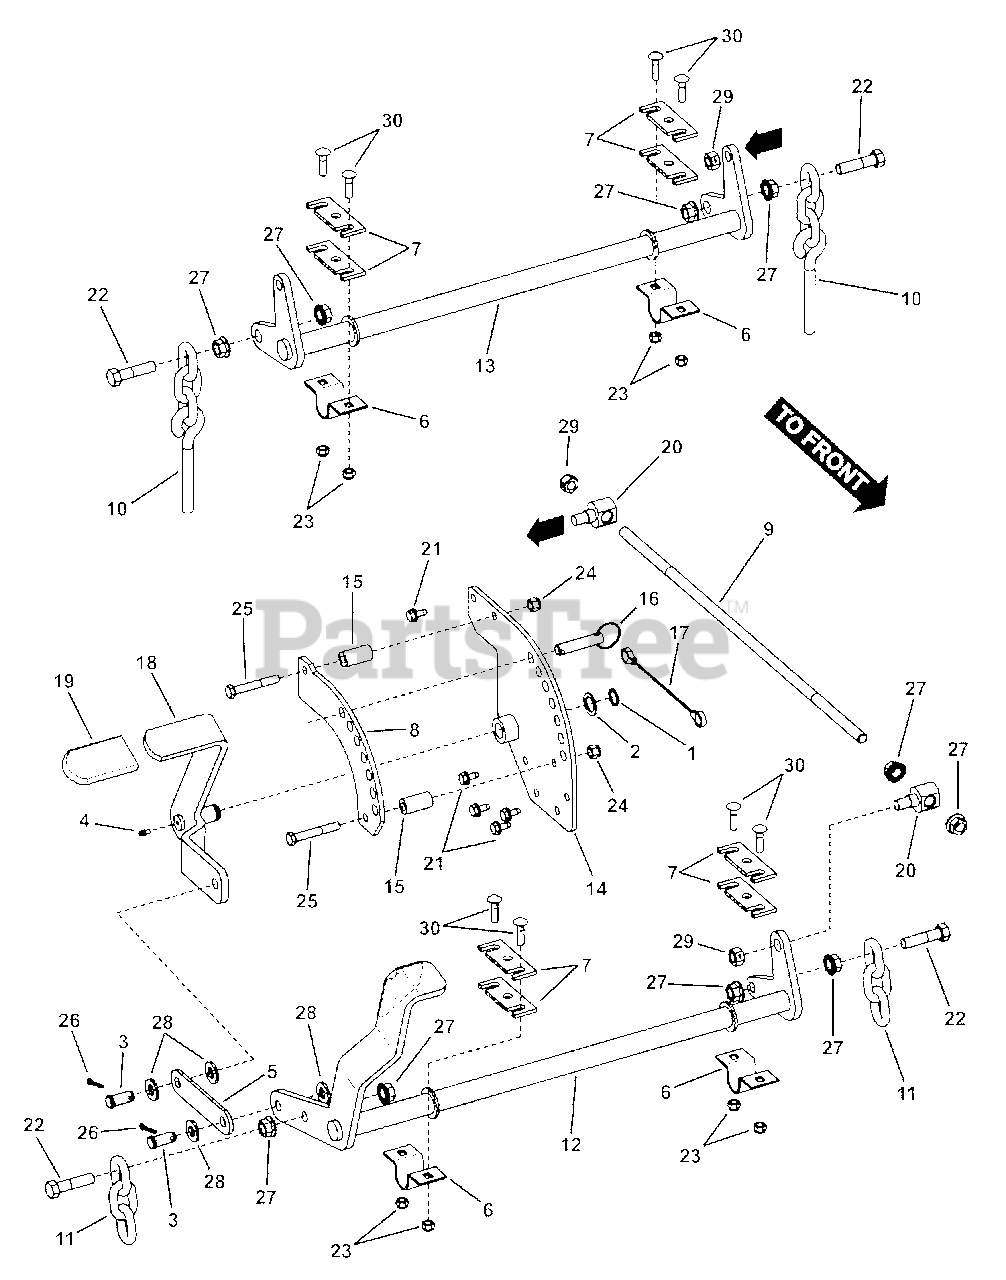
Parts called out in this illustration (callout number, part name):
1	RING, 3/4" External Retaining
2	WASHER, .77 I.D. Flat
3	PIN, 1/2 x 1-1/8" Clevis
4	LUBE FITTING, 3/16"
5	LINK, Lift
6	BRACKET, Deck Support
7	SHIM PLATE
8	PLATE, Height Support
9	TIE ROD, Lift (1/2-13 thread)
10	ASSY, Chain and Eyebolt
11	CHAIN LINKS
12	WELDMENT, Deck Lift Front
13	WELDMENT, Deck Lift Rear
14	WELDMENT, Deck Handle Support
15	SPACER, Lift Adjuster
16	CLIP, 1/2" Roll Pin
17	TETHER STRAP
18	WELDMENT, Lift Arm
19	GRIP (Plastic Cover)
20	SWIVEL, Rod (1/2-13 thread)
21	SCREW, 5/16-18 x 5/8" Hex Washer Self-Tap
22	SCREW, 1/2-13 x 2" Hex Head Cap, GR 5
23	NUT, 5/16-18 HEX NYLON LOCK
24	NUT, 3/8-16 HEX NYLON LOCK
25	BOLT, 3/8-16 X 2-1/2" GD5 CZ
26	COTTER PIN, 5/32 x 1"
27	NUT, 1/2-13 Hex Flange Lock, GR 5
28	WASHER, .531 I.D. Flat
29	NUT, 1/2-13 HEX SIDE LOCK
30	BOLT, 5/16-18 x 1-1/4" Square Neck Carriage, GR 5
